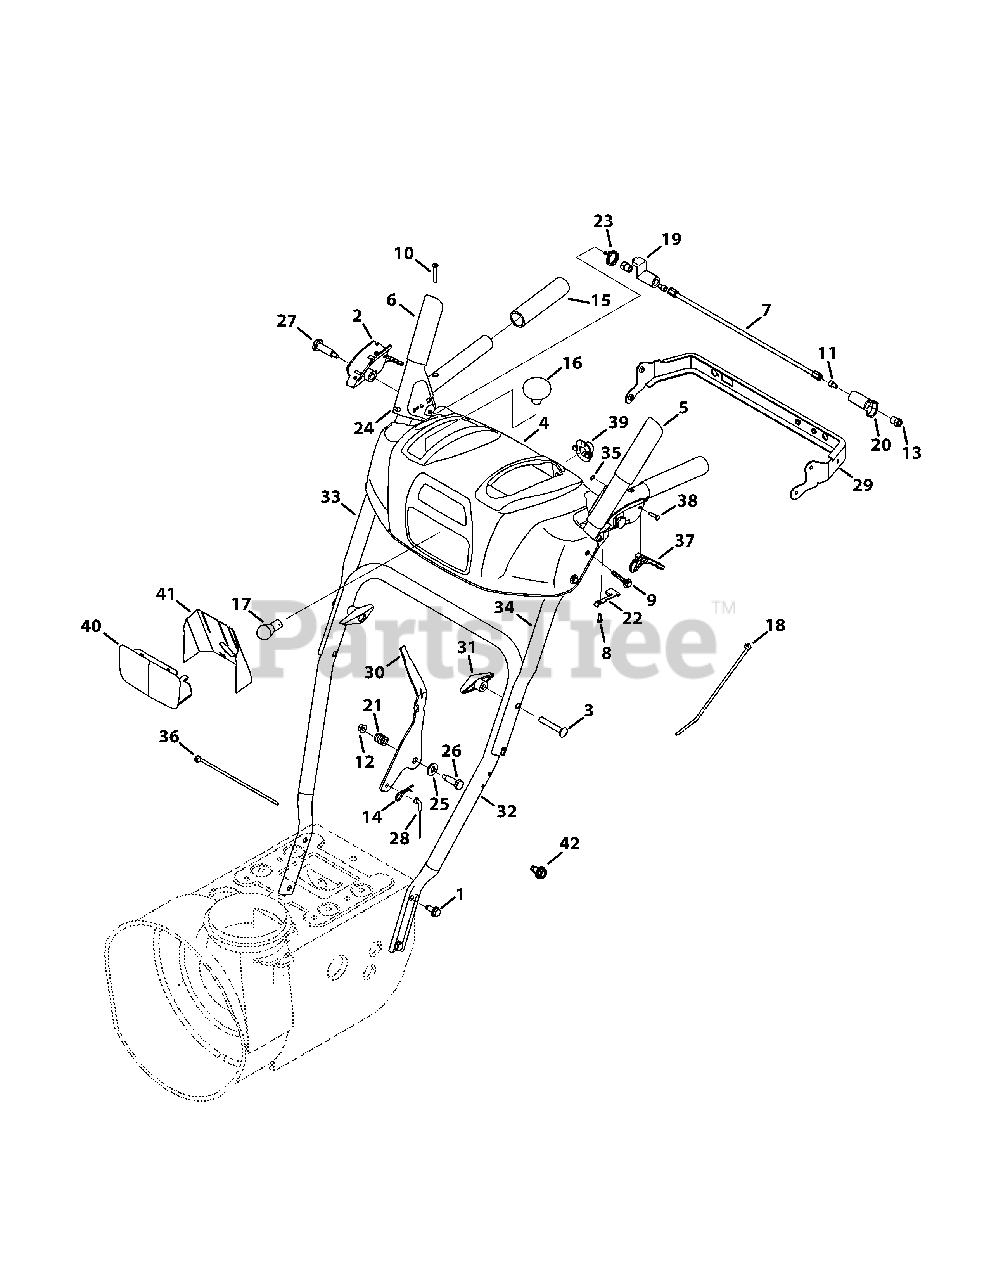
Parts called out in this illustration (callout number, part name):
1	Hex Screw, 5/16-18 x .750
2	Handle Clutch Lock LH Assy
2	Handle Clutch Lock RH Assy
3	Carriage Screw, 5/16-18 x 2.25
4	Handle Panel, includes Ref. 40 & 41
5	Handle Engagement Assembly LH
6	Handle Engagement Assembly RH
8	Screw, 8-16 x 0.50
9	Screw, 1/4-20 x 1.625
10	Screw, 10-24 x 1.375
11	Socket Screw, 1/4-20 x .50
12	Flange Lock Nut, 1/4-20
13	Shoulder Nut, 1/4-20
14	Click Pin, .092 x 1.64
15	Handle Grip (524/526/528 SWE)
16	Shift Knob
18	Cable Tie
20	Clutch Lock Cam
21	Compression Spring
22	Clutch Lock Spring
23	Torsion Spring
24	Rubber Bumper
25	Flat Washer, .385 x .87 x .06
26	Shoulder Screw, .374 x 1.05
27	Shoulder Screw, 1/4-20 x 1.345
28	Speed Cable Selector
29	Panel Bracket
31	Wing Knob
32	Lower Handle
33	Upper Handle RH
34	Upper Handle LH
36	Cable Tie
37	Clutch Trigger
39	Light Socket
41	Lens Label
42	Screw, TT, 1/4-20 x .500 (For ground wire)
